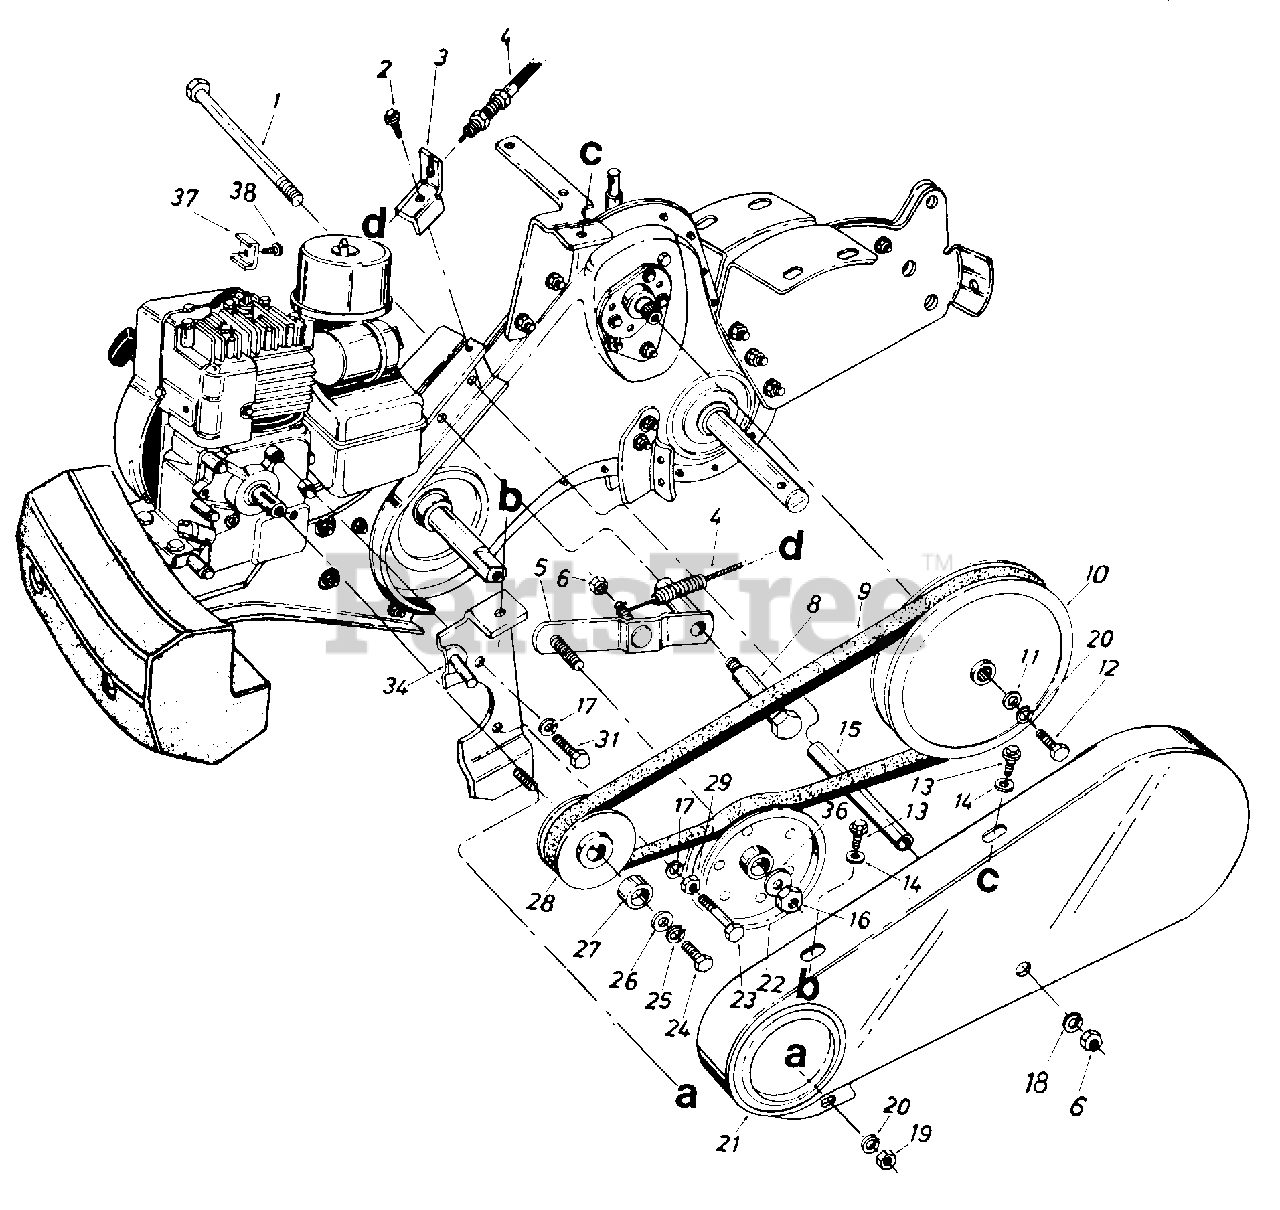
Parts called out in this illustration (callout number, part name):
1	Hex Bolt 5/16-18 x 4.75" Lg. Gr. 2
2	Hex Wash. TT-Tap Scr. 5/16-18 x .62" Lg.
3	Bracket Clutch Cable
4	Clutch Control Cable 53" Lg.
8	Shld. Bolt .500" Dia. x 2.27"
9	"V"-Belt 1/2" X 58.0" Lg.
10	"V"-Pulley Split 518" I.D.
11	Fl-Wash. 1/4" I.D. x .93" O.D.
12	Hex Bolt 1/4-28 x .75" Lg.
13	Hex Wash. Hd. S-Tap Scr. 1/4-20 x .50" Lg.
14	Fl-Wash. .281" I.D. x .625"
15	Spacer 3/8" I.D. x 3.38" Lg.
16	Hex Cent. L-Nut 3/8-24 Thd.
17	L-Wash. 5/16" I.D.
18	Fl-Wash. 5/16" I.D.
19	Hex Nut 1/4-20 Thd.
20	L-Wash. 1/4" I.D.
22	Fl-Idler w/Flanges 3.75" O.D.
23	Hex Bolt 5/16-24 x 1.75"
24	Hex Bolt 3/8-24 x 1.00" Lg.
25	L-Wash. 3/8" I.D.
26	Fl-Wash. 3/8" I.D. x 1.00"
27	Spacer .758" I.D. x .990'
28	Engine Pulley
29	Hex Nut 5/16-24 Thd.
31	Hex Bolt 5/16-24 x .62" Lg.
37	Casing Clamp
38	Hex Sems Scr. #10-32 x .62"
